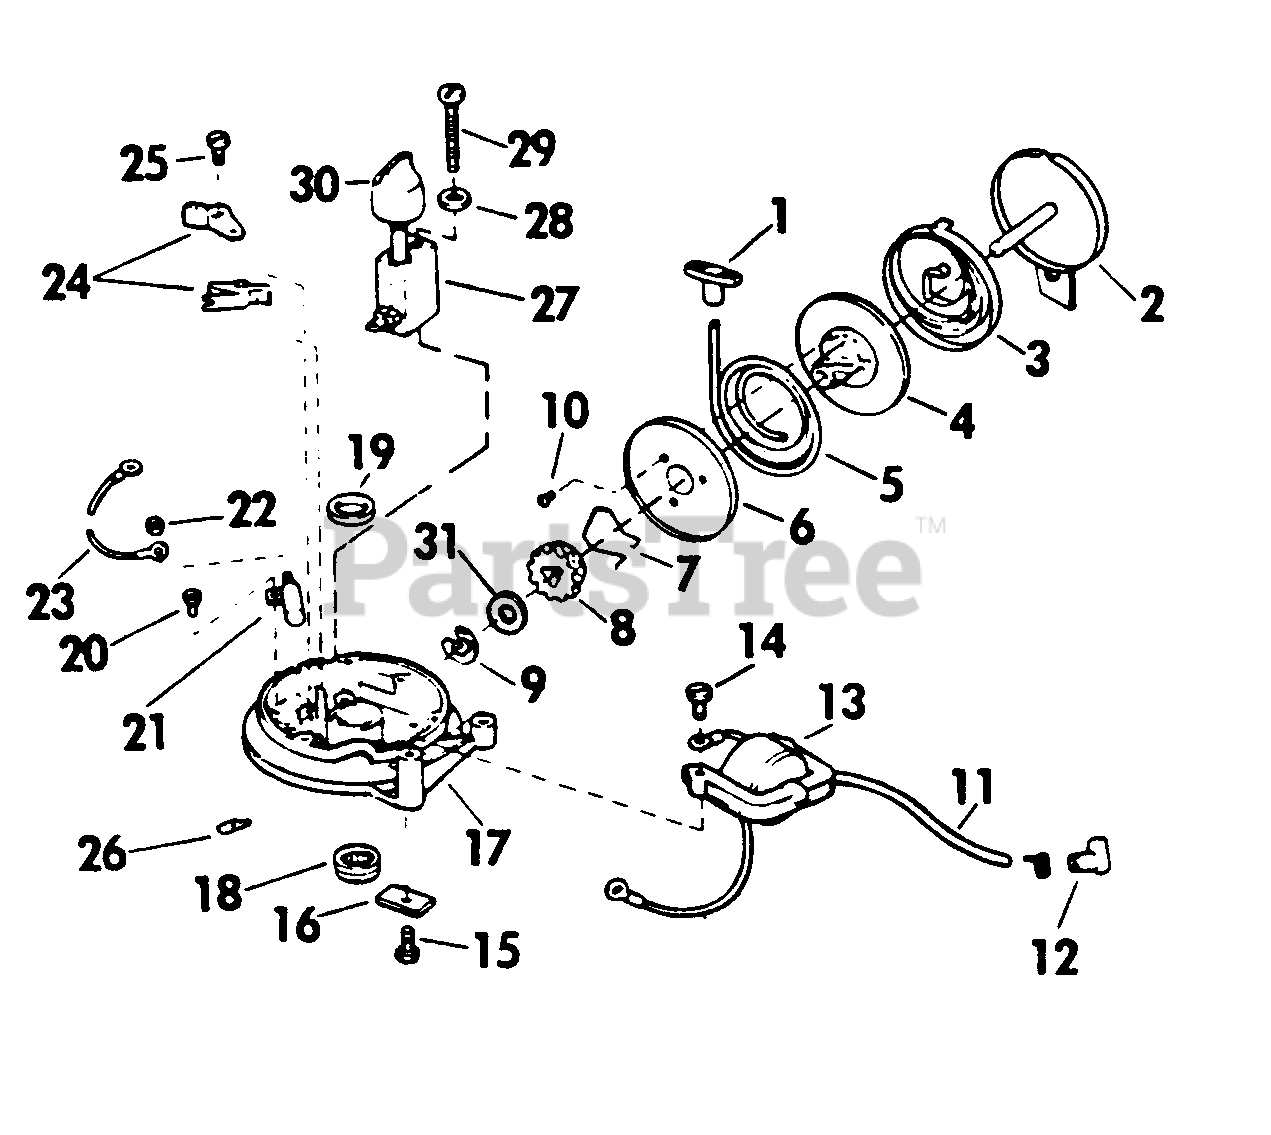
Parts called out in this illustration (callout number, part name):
1	Handle-Starter
2	Spring-Cup-Pin Assembly
3	Spring-Starter
4	Pulley-Starter
5	Rope-Starter
6	Plate-Starter Pulley
7	Spring-Starter Pinion
8	Pinion-Starter
9	Retainer-Push-On
10	Screw-Threaded Cutting Starter
11	High Tension Lead Assembly
12	Cover & Terminal Assembly
13	Coil & Lamination Assy.
14	Screw-Lamination Mounting
15	Screw-Starter Attach.
16	Clamp-Starter Pin
17	Arm. Plate Bearing & Oil Seal Assy.
18	Bearing
19	Oil Seal
20	Screw-Cond. Mtg.
21	Cond. & Nut Assy.
22	Nut
23	Terminal & Lead Assy.
24	Breaker Base & Arm Assembly
25	Screw-Breaker Base
26	Clip
27	Shorting Switch
28	Washer
29	Screw
30	Knob
31	Washer
